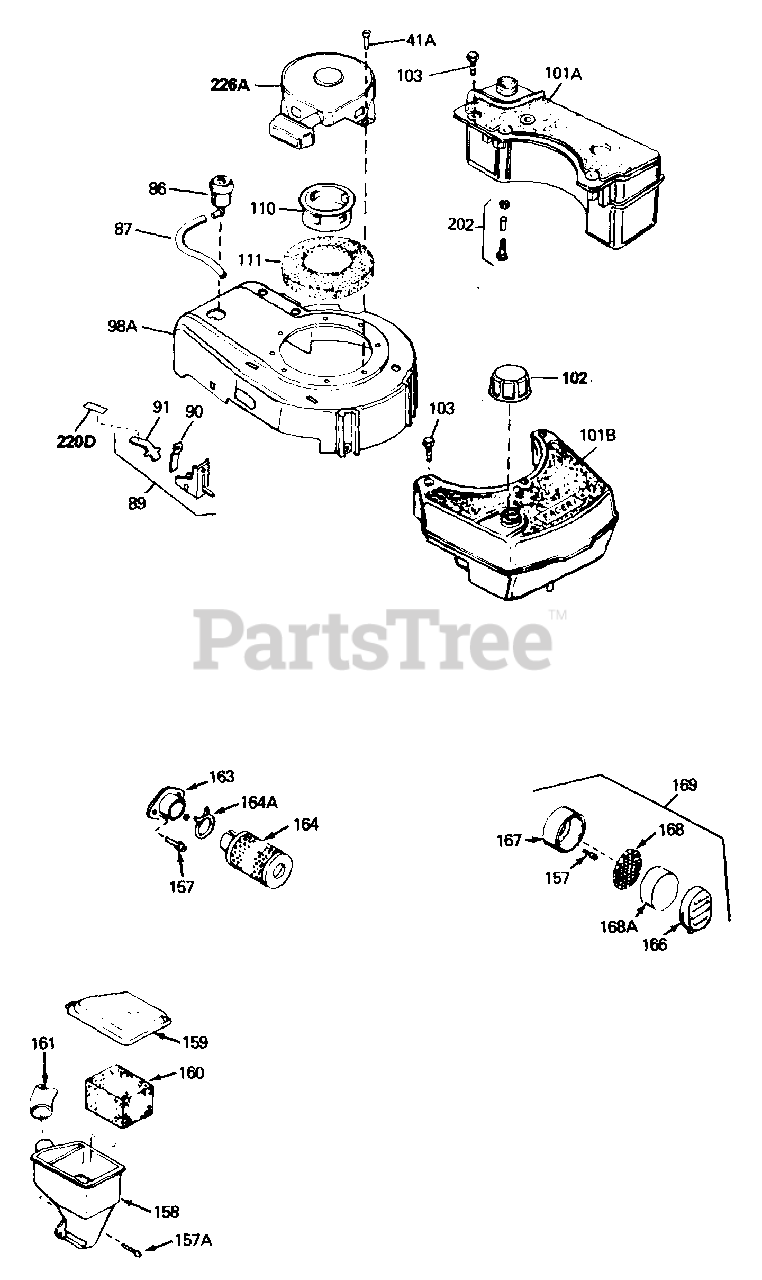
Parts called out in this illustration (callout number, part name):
41A	Rivet, Pop (3/16" Dia.)
41A	Screw, Hex hd. Sems taptite, 10-24 x 3/8
89	Footproof Spark Plug Stop Lever
90	Spring, Stop switch
91	Clip, Stop switch
98A	Housing, Blower (5.56 dia. starter mt g. bolt
102	Cap, Fuel filler (Red Plastic) (Spurt
110	Hub, Starter
111	Screen, Starter cup
157	Screw, Hex washer hd. shoulder, 10-32 x 5/8
202	Rope Guide Kit
220D	Decal, Stop control (Bilingual)
226A	Starter, Rewind
